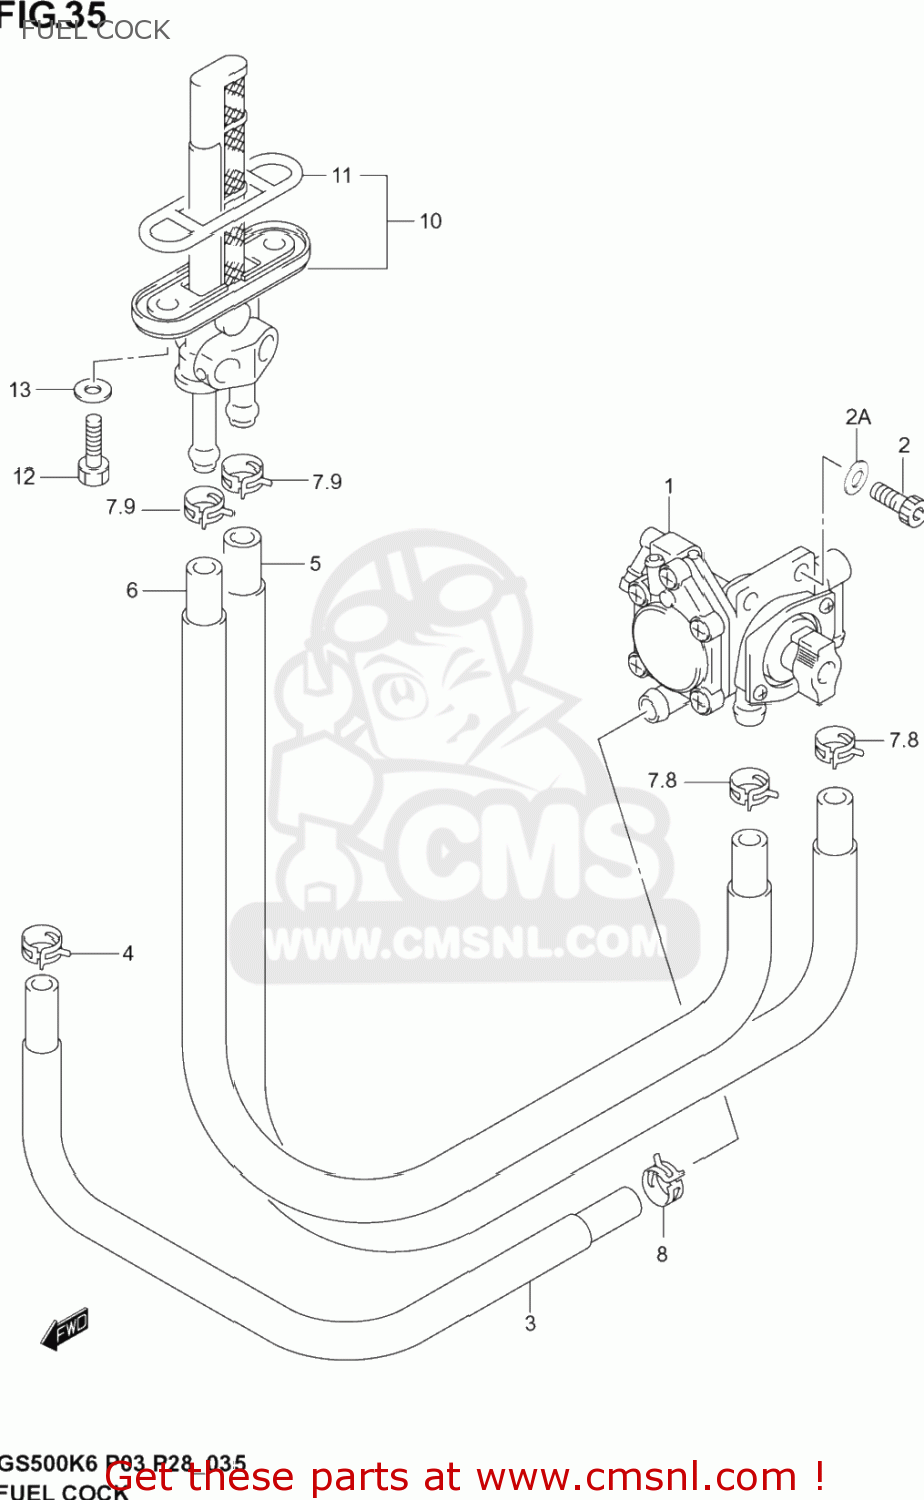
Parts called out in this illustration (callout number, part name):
1	COCK ASSY, FUEL
2	BOLT
2A	WASHER
3	HOSE, FUEL
4	CLIP
5	HOSE, FUEL "RES"
6	HOSE, FUEL "ON"
7	CLIP
8	CLIP
9	CLIP
10	COCK ASSY,FUEL NO.1
11	O RING,FUEL COCK
12	BOLT(6X20)
13	GASKET(6.4X11.5X0.8) (NAS)
